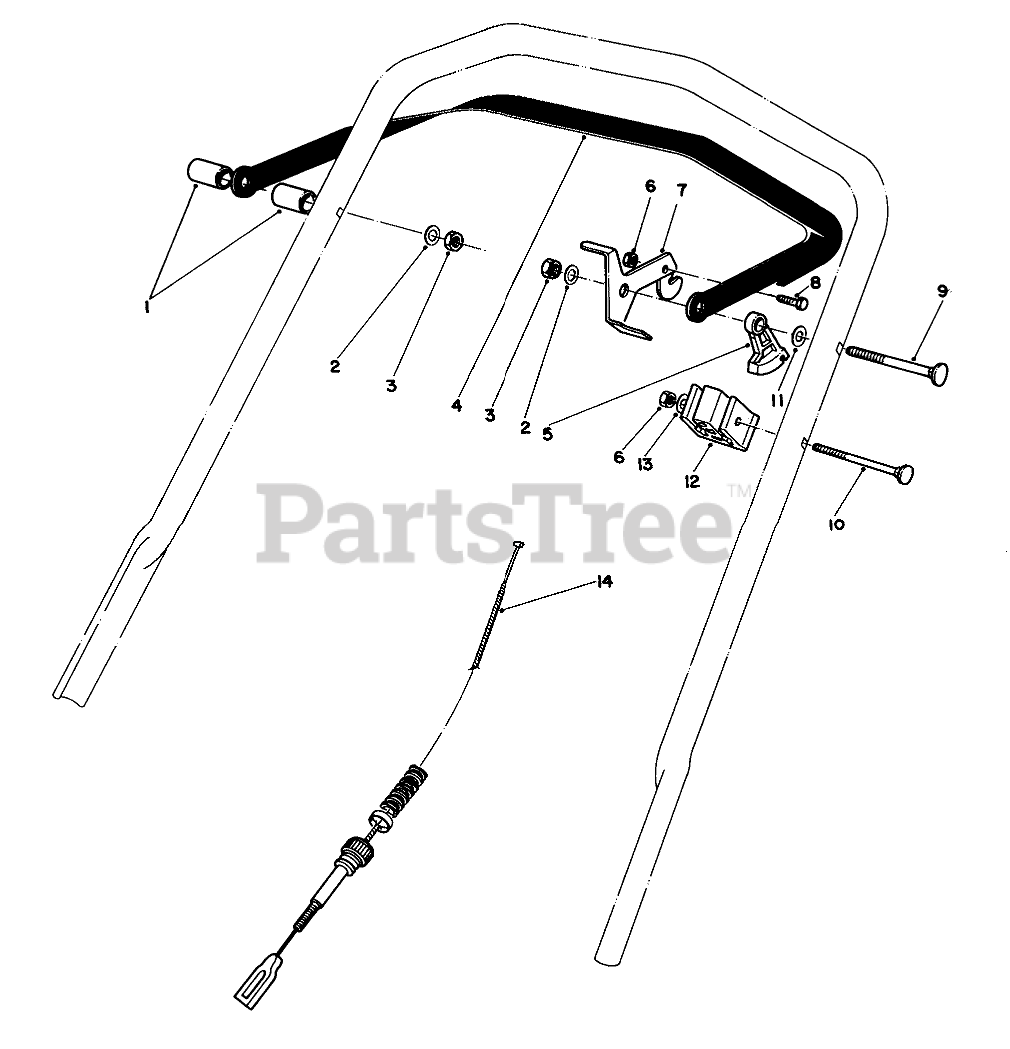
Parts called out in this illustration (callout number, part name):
1	Spacer
2	WASHER-PLAIN
3	NUT-LOCK, NI
4	Bar-Control
5	LEVER-TRACTION
6	NUT-LOCK, NI
7	CONTROL LEVER
8	SCREW-HH
9	5/16-18 X 2 HNDLE SCREW
10	SCREW-HANDLE
11	WASHER-FLAT
12	SUPPORT-CABLE
13	WASHER-FLAT
14	CABLE-TRACTION
